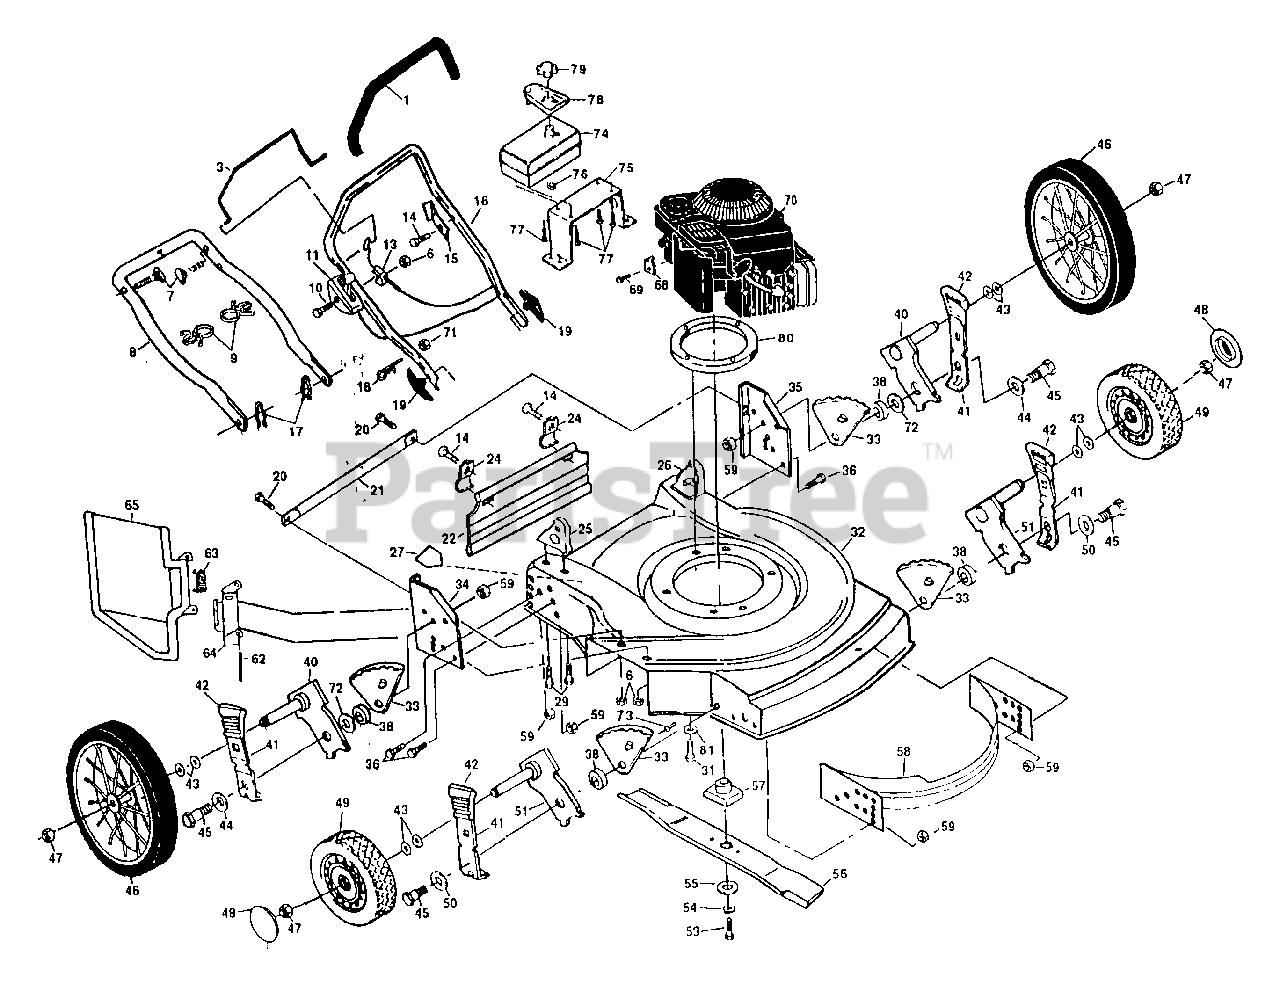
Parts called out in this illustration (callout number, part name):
1	Handle Grip (AYP part number)
3	Control Bar (AYP part number)
6	Locknut 1/4-20 (AYP part number)
7	Handle Bolt 5/16-18 x 1-3/4 (AYP part number)
8	Lower Handle (AYP part number)
9	Cable Clip (AYP part number)
10	Hex Washer Head Screw 1/4-20 x 2-1/8 (AYP part number)
11	Throttle Control
13	Engine Zone Control Cable
14	Hex Washer Head Screw #10-24 x 1/2 (AYP part number)
15	Up-Stop Bracket (AYP part number)
16	Upper Handle (AYP part number)
17	Hairpin Cotter (AYP part number)
18	Rope Guide
19	Handle Knob (AYP part number)
20	Self-tapping Screw 1/4-20 x 1/2 (AYP part number)
21	Support Rod (AYP part number)
22	Rear Skirt (AYP part number)
24	Skirt Bracket (AYP part number)
25	Handle Bracket Assembly (Right) (AYP part number)
26	Handle Bracket Assembly (Left) (AYP part number)
27	Danger Decal (AYP part number)
29	Thread Cutting Screw 5/16-18 x 1-3/4 (AYP part number)
31	Thread Rolling Screw 3/8-16 x 1 (AYP part number)
32	Lawn Mower Housing
33	Wheel Adjusting Bracket (AYP part number)
34	Wheel Support Bracket (Right) (AYP part number)
35	Wheel Support Bracket (Left) (AYP part number)
36	Hex Head Bolt 3/8-16 x 3/4 (AYP part number)
38	Spacer (AYP part number)
40	Axle Arm Assembly (Rear) (AYP part number)
41	Selector Spring (AYP part number)
42	Selector Knob
43	Washer (AYP part number)
44	Washer (AYP part number)
45	Shoulder Bolt 3/8-16 (AYP part number)
46	Wheel 8 Tire Assembly (AYP part number)
47	Locknut (AYP part number)
48	Hubcap (AYP part number)
49	Wheel & Tire Assembly
50	Washer (AYP part number)
51	Axle Arm Assembly (Front) (AYP part number)
53	Hex Head Screw 3/8-24 x 1-3/8 Gr. 8
54	Helical Washer 3/8 (AYP part number)
55	Hardened Washer (AYP part number)
56	22" Blade (AYP part number)
57	Blade Adapter (AYP part number)
58	Front Baffle & Rear (AYP part number)
59	Locknut 3/8-16 (AYP part number)
62	Hinge Rod (AYP part number)
63	Torsion Spring (AYP part number)
64	Housing Bracket Assembly (AYP part number)
65	Discharge Guard (AYP part number)
68	Cable Clamp (AYP part number)
69	Thread Rolling Screw #10-32 x 5/8 (AYP part number)
71	Locknut, Keps 1/4 20 (AYP part number)
72	Flat Washer 3/8 (AYP part number)
73	Pop Rivet (AYP part number)
74	Fuel Tank (AYP part number)
75	Fuel Tank Bracket (AYP part number)
76	Clamp (AYP part number)
77	Tapping Screw
78	Deflector (AYP part number)
79	Fuel Cap (AYP part number)
80	Spacer (AYP part number)
81	Washer (AYP part number)
